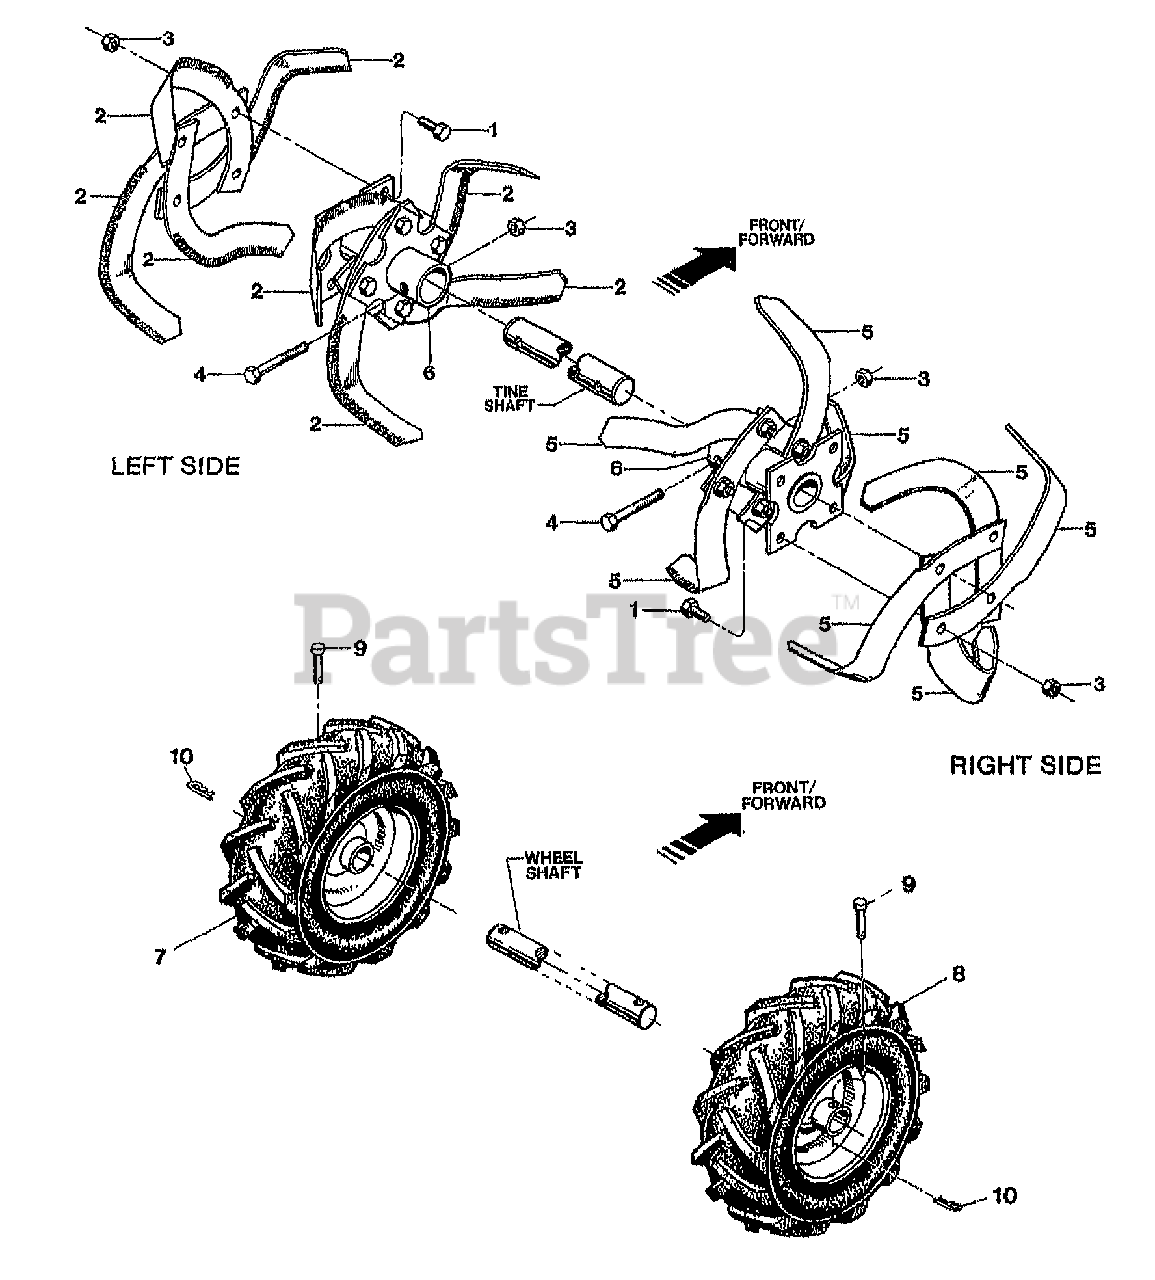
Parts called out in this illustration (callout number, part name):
1	SCR-HH 3/8-16X1.0 G5 ZP
2	TINE-BOLO RIGHT
3	NUT-LOCK 3/8-16
4	SCR-HH 3/8-16X2.00 G8 (TINE HOLDER TO TILLER SHAFT)
5	TINE-BOLO LEFT
6	HOLDER-TINE JUNIOR
6	HOLDER-TINE T/B TUFFY {12155}
7	ASSM-TIRE&WHL LH GRAY
8	ASSM-TIRE&WHL RH GRAY
9	PIN-CLEVIS
10	PIN-CLIP .08
